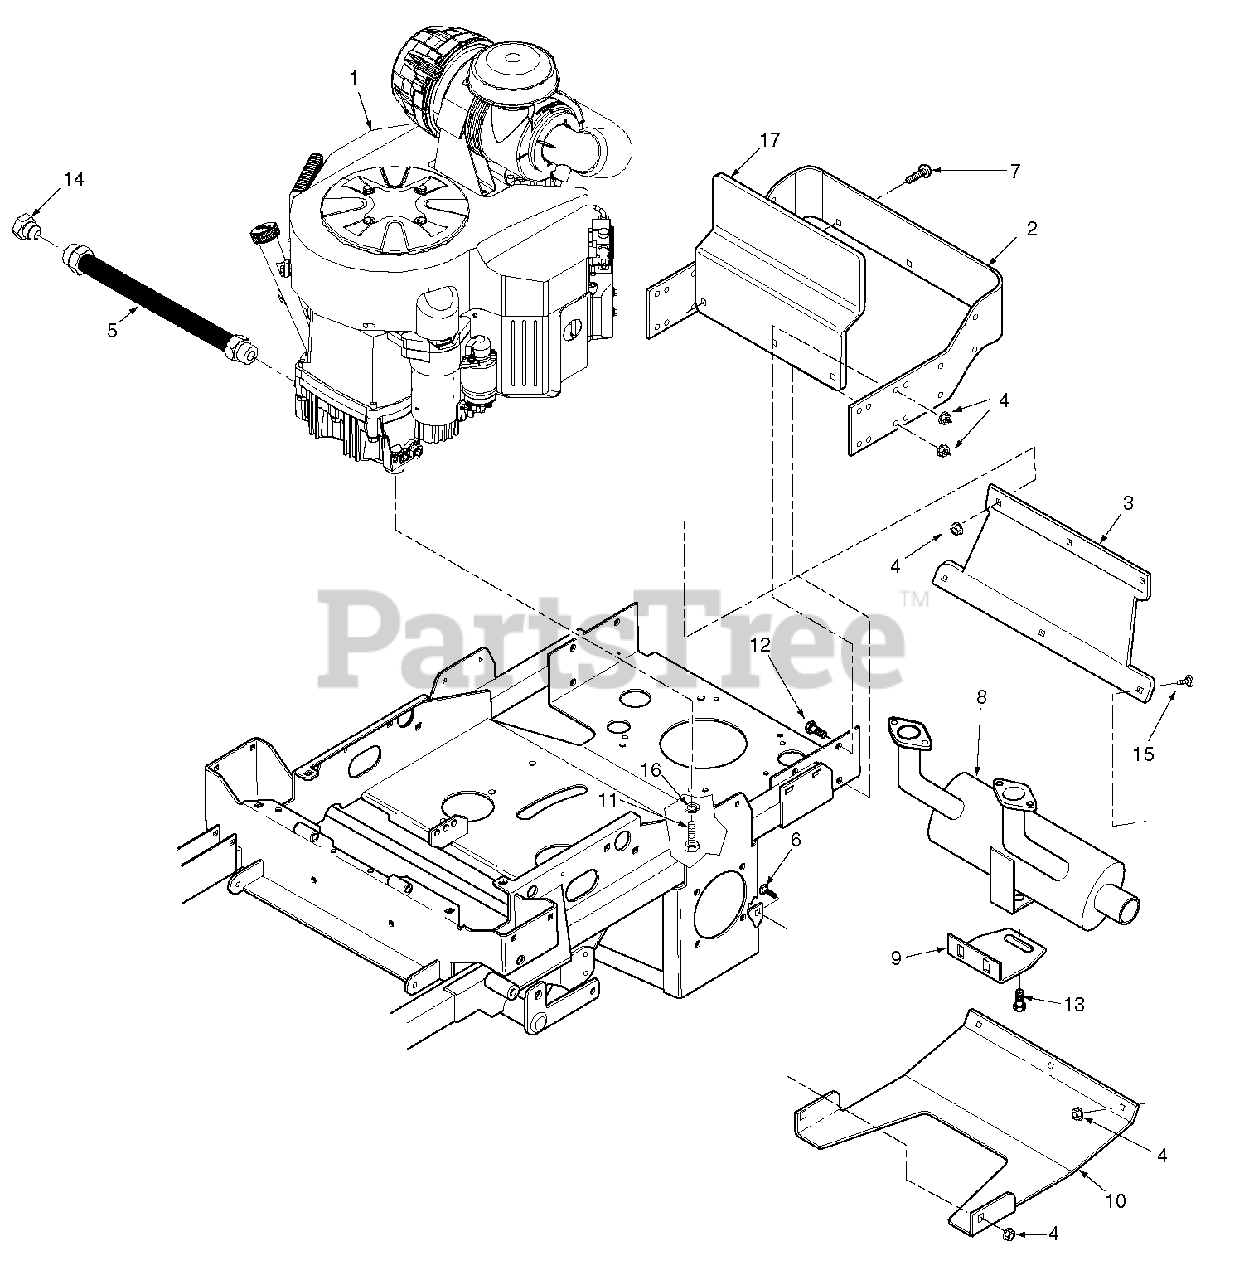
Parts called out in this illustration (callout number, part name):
1	Engine,
2	Bumper, Rear
3	Shield, Rear
3	Weight, Rear Shield
4	Nut, Serr. Flange 3/8-16
5	Hose, Oil Drain
6	Bolt, Carr. 3/8-16 x 1"
7	Bolt, 3/8-16 x 1" Torx
8	Muffler
9	Bracket, Muffler
10	Plate, Skid
11	Bolt, Hex Head 3/8-16 x 1-1/4"
11	Bolt, Hex Head 3/8-16 x 1-1/4" Self Tap
11	Bolt, Hex Head 5/16-18 x 1-1/2"
11	Nut, Serrated Flange 5/16-18
12	Bolt, Hex Head 3/8-16 x 1"
13	Screw, Hex Head 5/16-18 x 3/4" Self Tap
14	Tubing, Oil Drain 1/2" x 8"
15	Bolt, Carr. 3/8-16 x 3/4"
16	Nut, Serr. Flange 5/16-18
17	Guard, Carb Inlet
